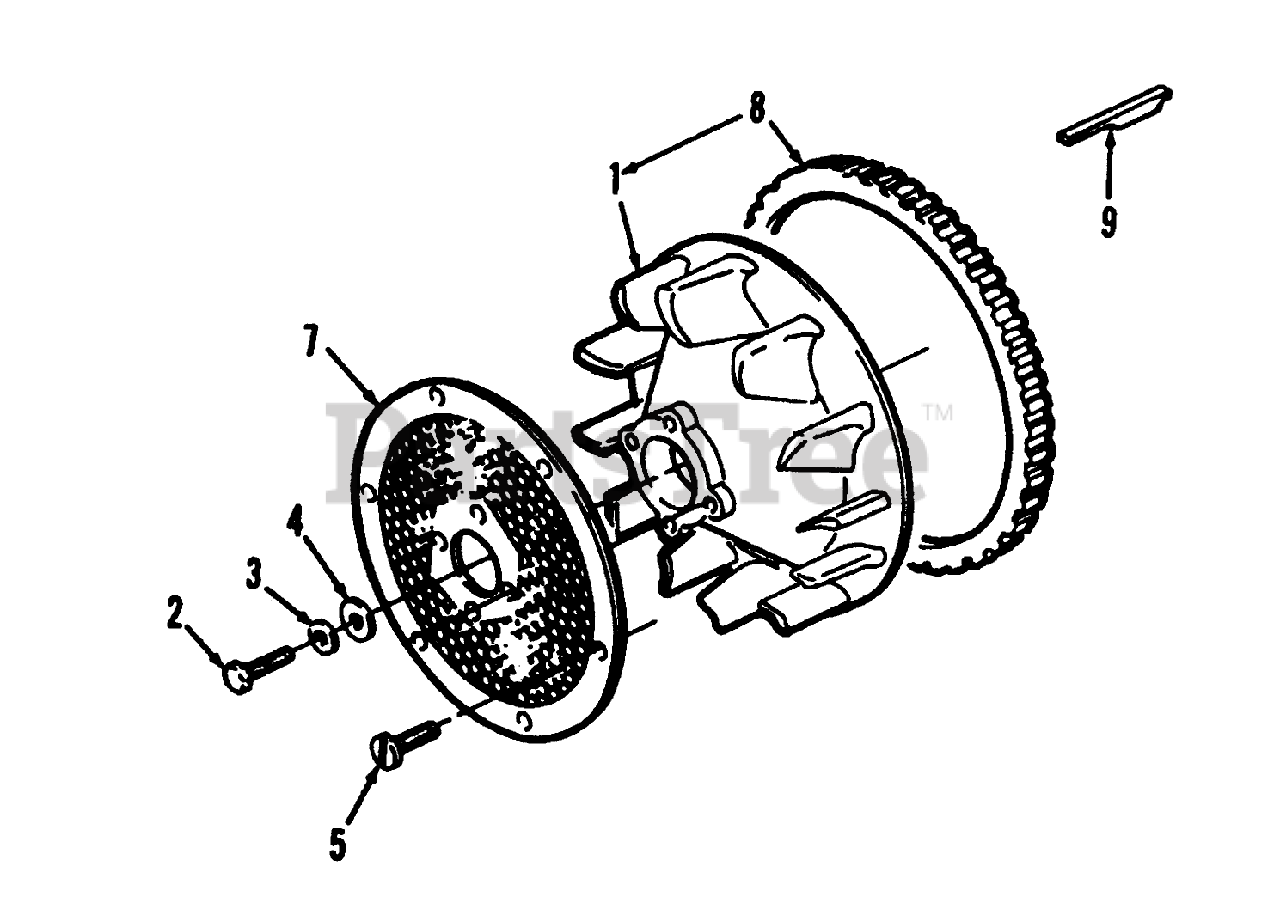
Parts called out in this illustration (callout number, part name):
3	WASHER-FLAT
4	WASHER-FLAT
7	SCREEN-AIR INLET
